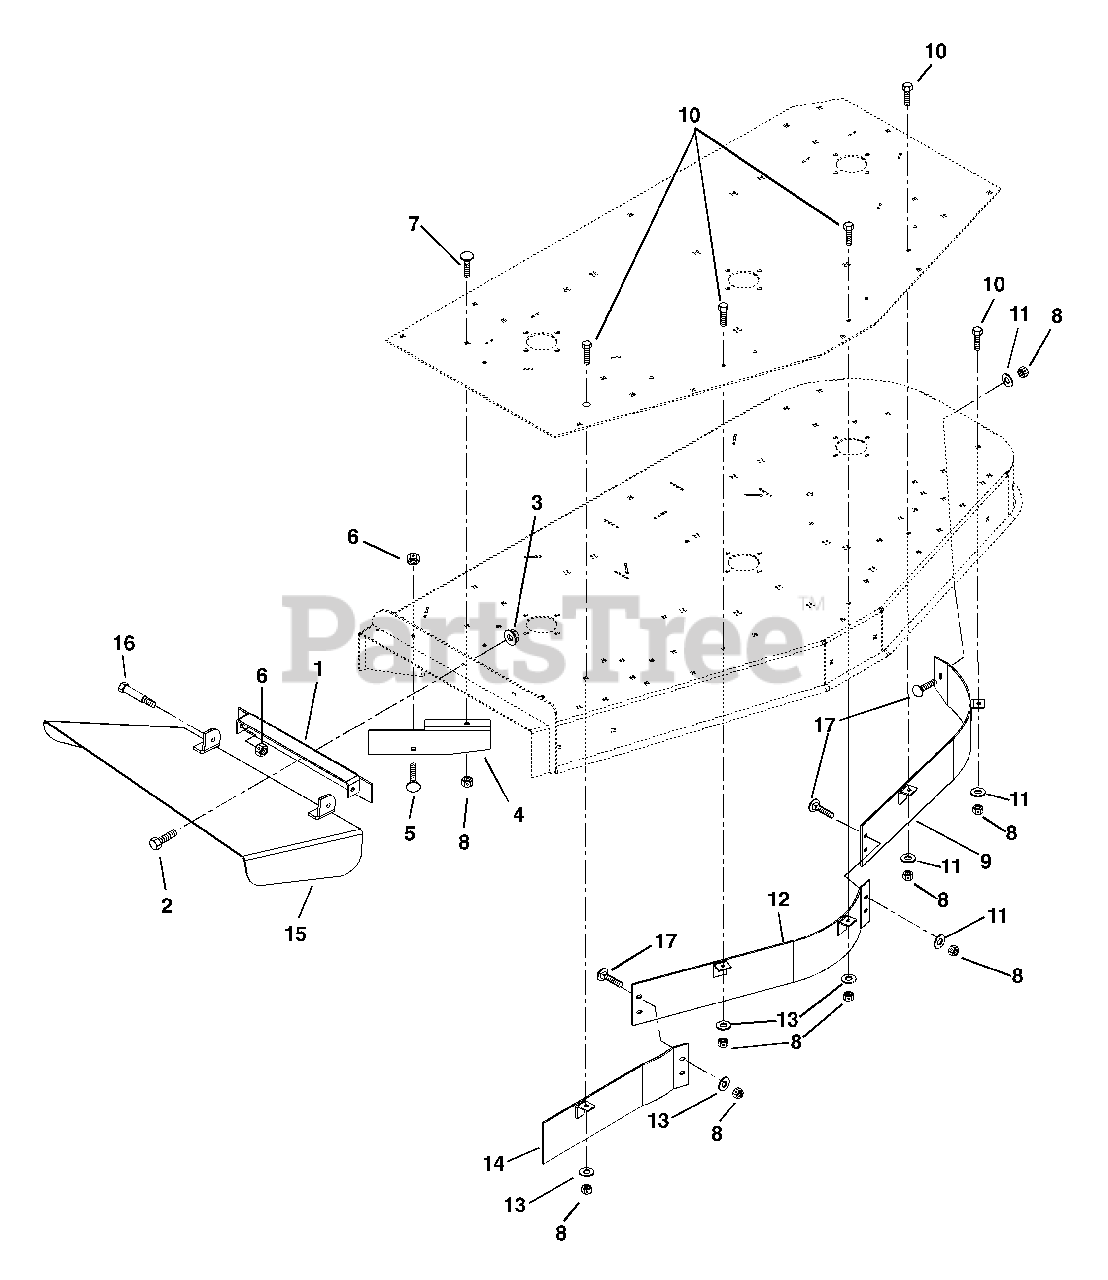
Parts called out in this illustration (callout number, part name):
1	Weldment, Discharge Chute Bracket
2	Bolt-Hex .38 - 16 x 1.00 Grade 5
3	Nut-Locking-Flange .38 - 16
4	Deflector, 72"
5	Bolt-Round Head Square Neck .38 - 16 x 1.00 Grade 2
6	Nut-Locking-Center .38 - 16
7	Bolt-Round Head Square Neck .31 - 18 x 1.00 Grade 5
8	Nut-Locking-Nylon .31 - 18
9	Weldment, 72" Left Hand Baffle
10	Bolt-Hex .31 - 18 x 1.00 Grade 5
11	Washer-Flat-Steel .312 x .734 x .065
12	Weldment, 72" Center Baffle
13	Washer-Flat-Steel .312 x .734 x .065
14	Weldment, 72" Right Hand Baffle
15	Weldment, Discharge Chute 72"
16	Bolt-Shoulder .38 - 16 x .38
17	Bolt-Round Head Square Neck .31 - 18 x .75 Grade 2
18	72" S.D. Mulch Kit
19	72" Discharge Cover Kit
